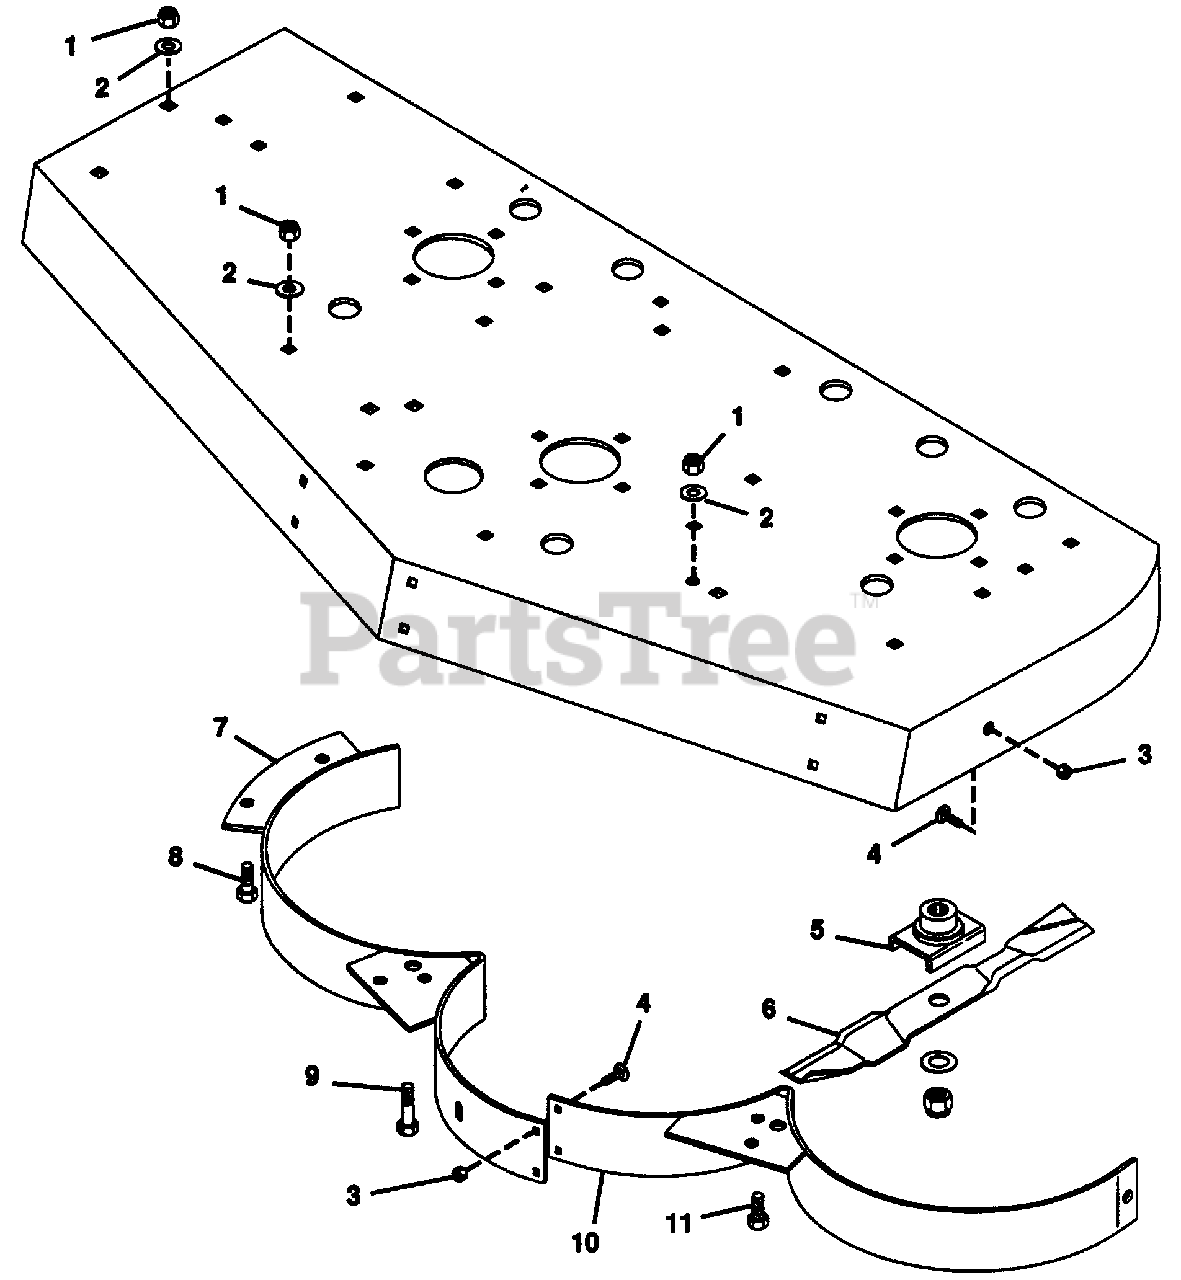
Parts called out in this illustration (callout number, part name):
1	Nut, Lock 3/8-16
2	Washer, Flat .406x.812x.065
3	Nut, Lock 1/4-20
4	Bolt, 1/4-20x.625 Rd Hd Sq Nk
5	Weldment, Blade Cradle
6	Blade, Mulching 40" Mower
7	Weldment, Discharge Baffle
8	Bolt, Hex 3/8-16x1.00
9	Bolt, Hex 3/8-16x1.75
10	Weldment, Mulching Baffle
11	Bolt, Hex 3/8-16x.75
